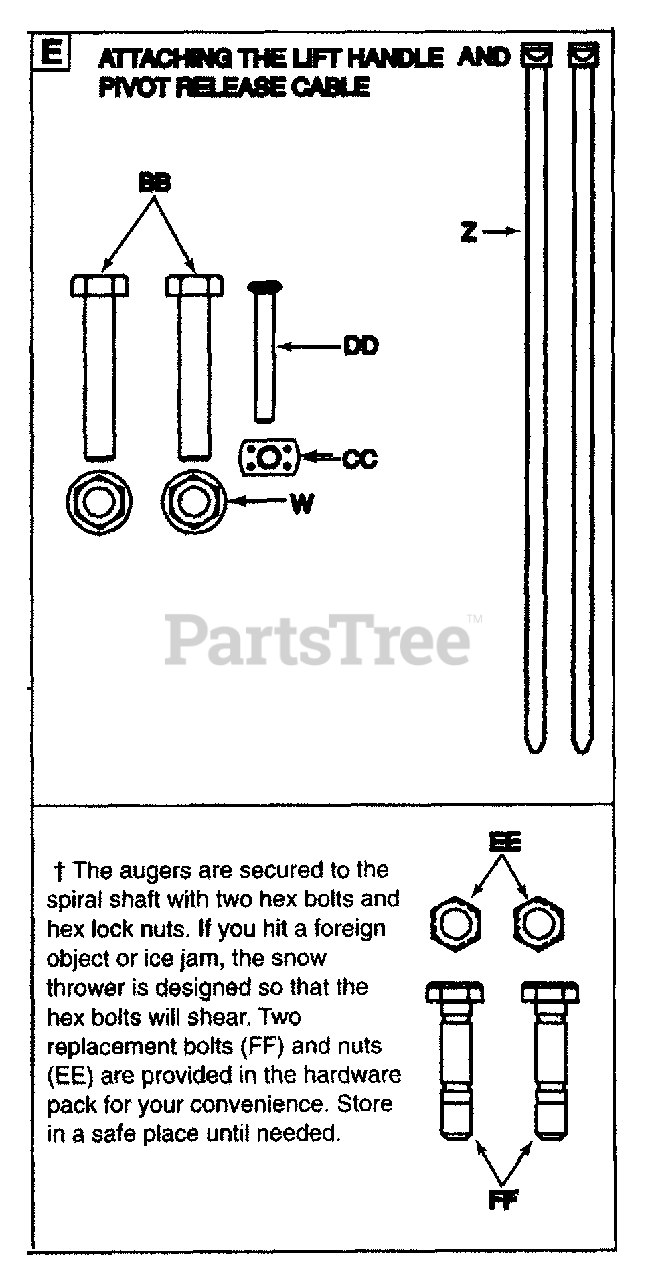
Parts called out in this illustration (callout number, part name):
W	Hex Flange Lock Nuts 5/16-18 Thread
BB	Hex Bolts 5/16-18 x 1.75" Long
CC	Flat Weld Nut #10-24 Thread
DD	Truss Machine Screw #10-24 x 1.36" Long
EE	Hex Lock Nuts 5/16-18 Thread
FF	Shear Bolts 5/16-18 x 1.5" Long
